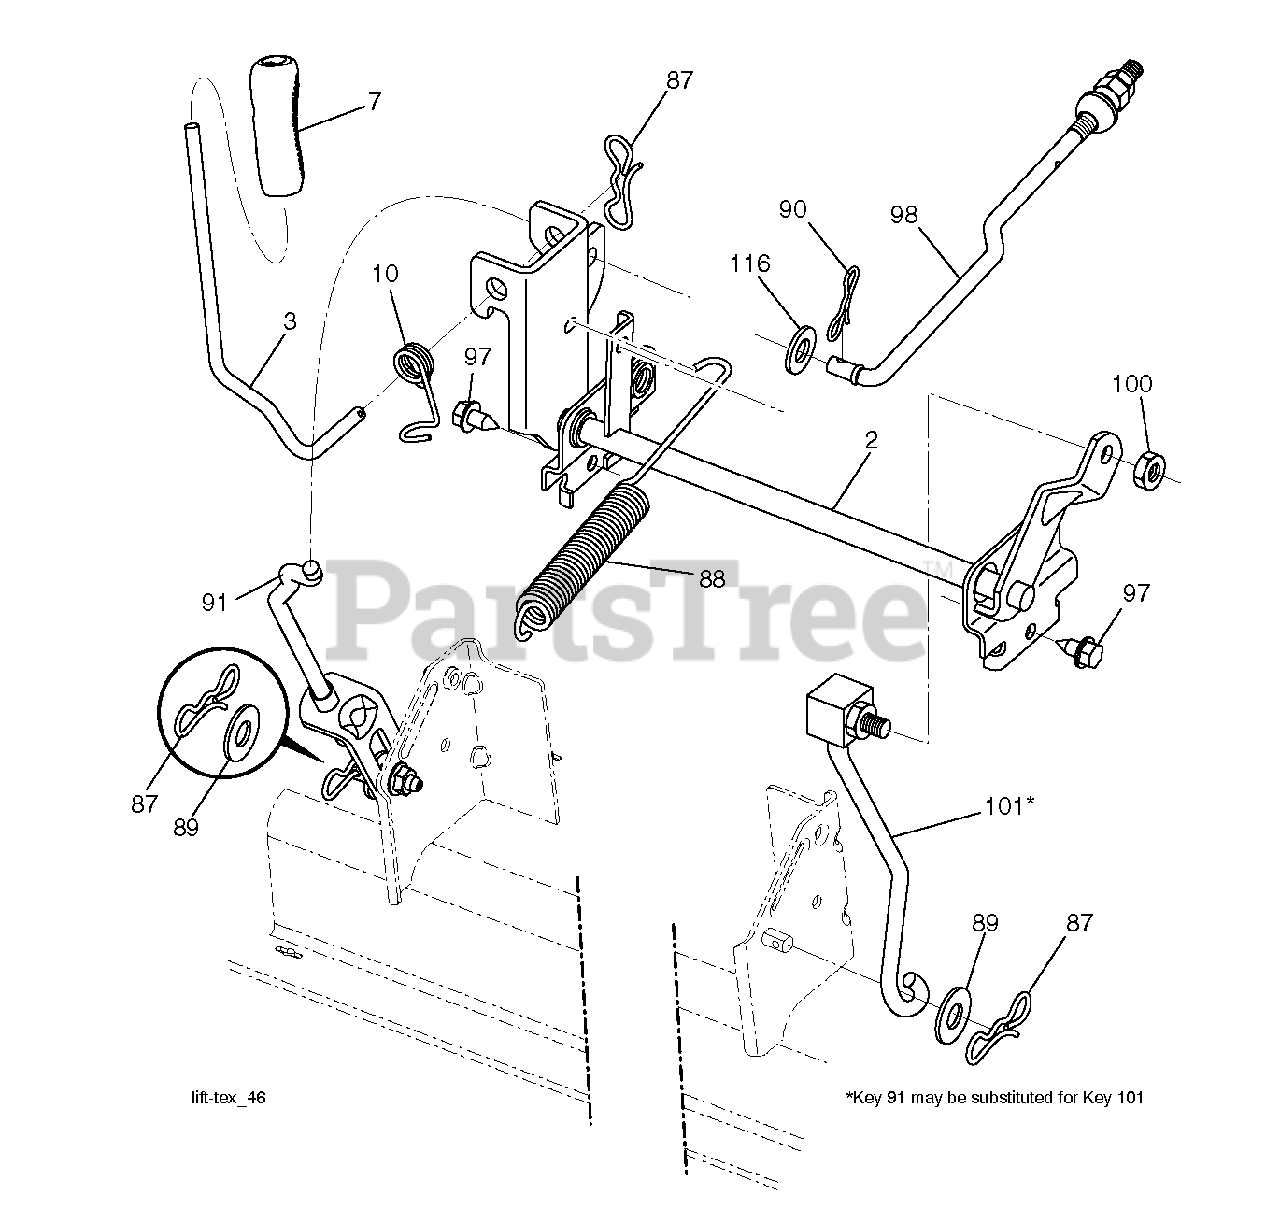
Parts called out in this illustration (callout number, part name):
2	SHAFT.ASM.CROSS.LIFT
3	LEVER.LIFT.HANDLE.LT
7	GRIP.HANDLE.LIFT.PVC.BLACK
10	SPRING.TORSION.LIFT.HANDLE
87	PIN.COTTER.7/16.BOW TI.
88	SPRING.LIFT.ASSIST
89	WASHER.CLEAR.ZINC
90	PIN.COTTER.5/16.BOW TI
91	LINK.LIFT.ASM.REAR.GT.
97	SCREW, 3/8-16X3/4
98	LINK.FRONT.MOWER.SUSP.ASM.BLK
100	LOCKNUT
